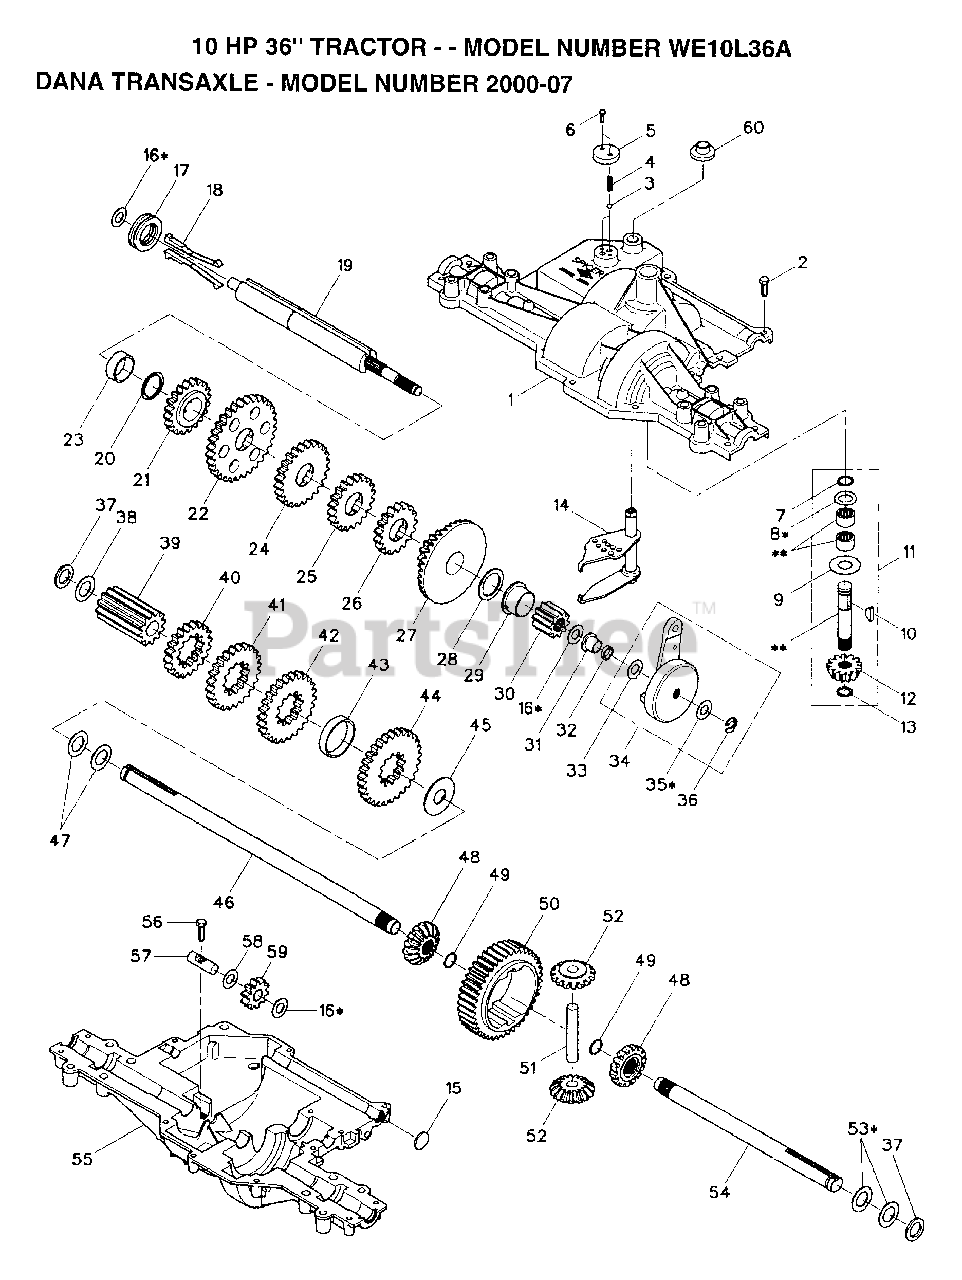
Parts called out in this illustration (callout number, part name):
1	HOUSING, UPPER
3	BALL, DETENT
4	SPRING, DETENT
5	COVER, DETENT
7	RING RETAINING
8	ASSY, KIT, SHIM .625 SHAFT
9	WASHER, PLAIN .632 X 1.38 X .046
10	KEY WOODRUFF #9
11	ASSY, KIT, INPUT SHAFT
12	PINION, BEVEL
13	RING, RETAINING
14	ASSY, SHIFTER
16	ASSY, KIT, SHIM
17	COLLAR CLUTCH
18	ASSY, KIT, CLUTCH KEYS
19	SHAFT, DRIVE
20	RING, RETAINING
21	GEAR, SPUR, 20T
22	GEAR, SPUR, 32T
24	GEAR, SPUR, 24T
25	GEAR, SPUR, 20T
26	GEAR, SPUR, 17T
27	GEAR, BEVEL, 39T & SPUR 15T
30	GEAR, SPUR, 10T
33	WASHER PLAIN
34	ASSY, KIT, BRAKE CONE
35	ASSY, KIT, SHIM
37	WASHER, NEOPRENE
38	WASHER PLAIN
39	GEAR, SPUR, 12T
40	GEAR, SPUR, 20T
41	GEAR, SPUR, 24T
42	GEAR, SPUR, 26T
44	GEAR, SPUR, 29T
47	WASHER, PLAIN .758 X 1.25 X .031
48	GEAR, MITER, 15 TEETH
49	RING, RETAINING
50	GEAR, SPUR, 41T
51	SHAFT, CROSS
52	GEAR, MITER, 15 TEETH
53	ASSY, KIT, SHIM .750 SHAFT
55	HOUSING, LOWER
56	SCREW 1/4-20 X .875
57	SHAFT, IDLER
58	WASHER PLAIN
59	GEAR, SPUR, 10T
60	BOOT, SHIFTER
